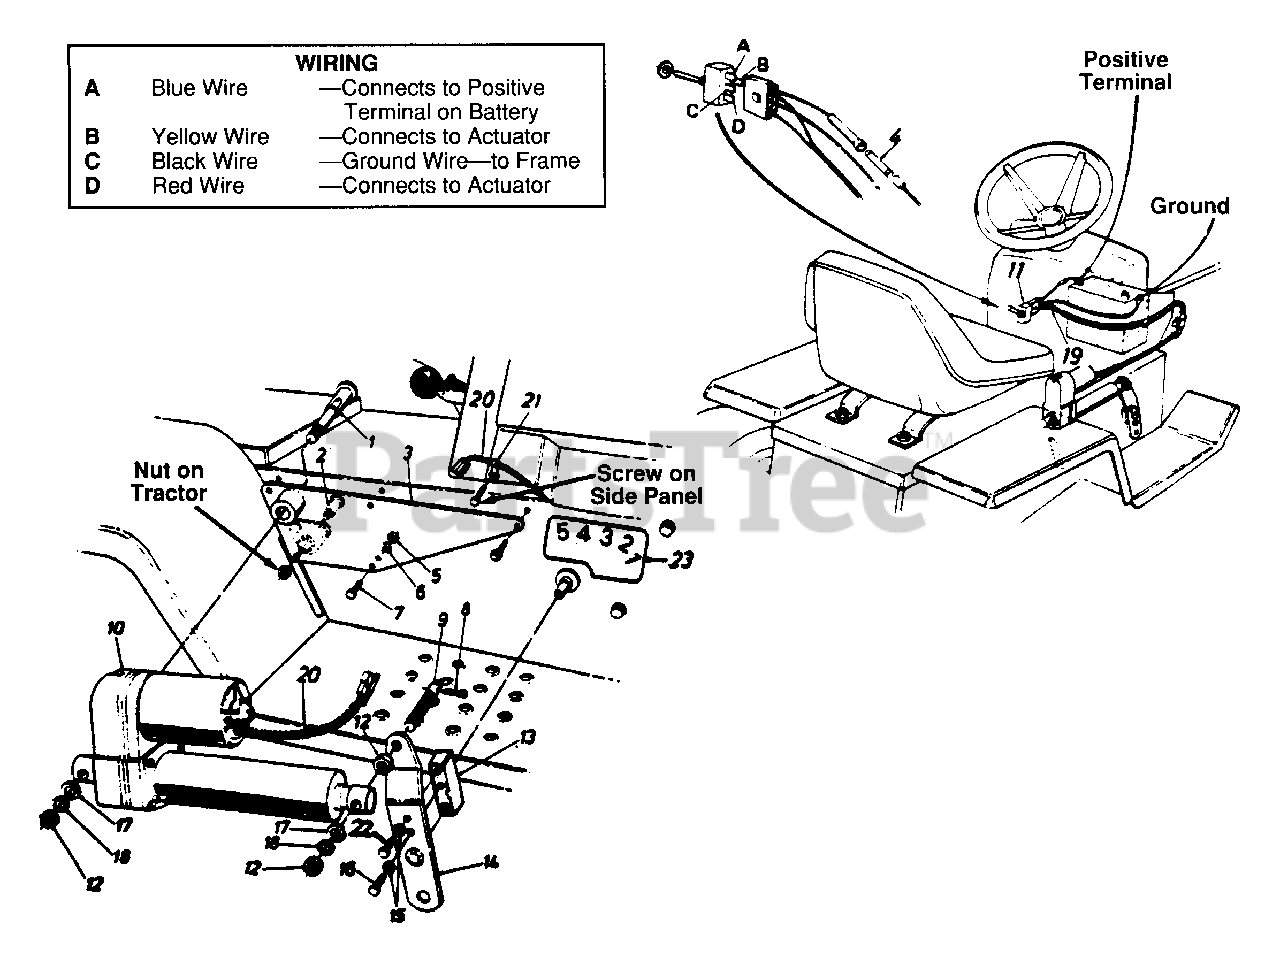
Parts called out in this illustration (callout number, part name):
2	Shld. Bolt .626" Dia. x .96"
5	Hex Nut 1/4-28 Thd.
6	L-Wash. 1/4" I.D.
7	Hex Bolt 1/4-28 x .75" Lg. (Grade 5)
9	Indicator & Mtg. Pin
10	Electric Actuator
11	Toggle Switch
12	Hex Jam Nut 1/2-13 Thd.
13	Lift Shaft Drive
16	Hex Bolt 5/16-24 x 1.0" Lg. (Grade 5)
17	Fl-Wash. .53" I.D. x .93" O.D.
18	L-Wash. 1/2" I.D.
19	Wire Harness
20	Plastic Tubing - 7"
22	Hex Bolt 5/16-18 x 1" Lg. (Grade 5)
23	Label
A	Blue Wire
B	Yellow Wire
C	Black Wire
D	Red Wire
